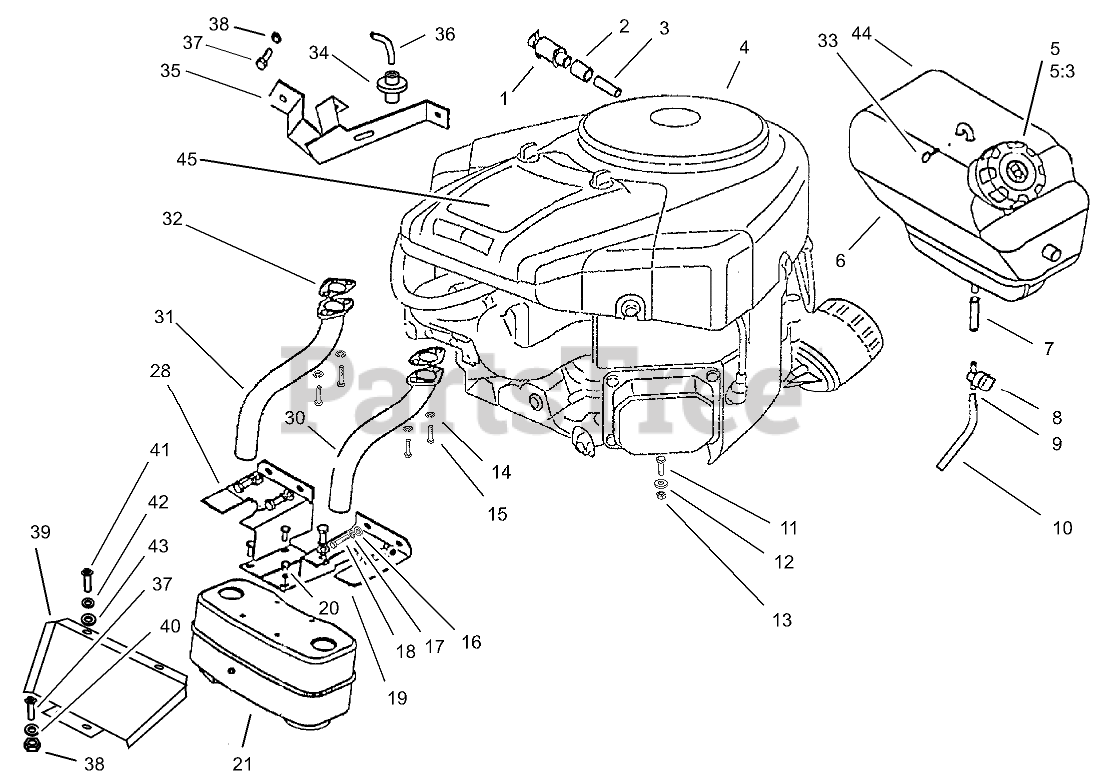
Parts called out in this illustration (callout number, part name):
1	VALVE-OIL DRAIN
2	COUPLER-OIL DRAIN
3	FITTING-OIL DRAIN
4	Engine-Briggs, Intek, 2cyl
5	GAS CAP ASM
5:3	GASKET-CAP, GAS
6	TANK-FUEL
7	LINE-FUEL
8	VALVE-TANK, FUEL
9	CLAMP-LINE, FUEL
10	LINE-FUEL
11	BOLT-HHF
11	SCREW
12	WASHER-PLAIN
13	NUT-LOCK, NI
14	WASHER-SPRING
15	SCREW-HH
16	WASHER-PLAIN
17	WASHER-SPRING
18	SCREW-HH
19	GUARD-MUFFLER, LH
20	SCREW-HWH
21	MUFFLER
28	GUARD-MUFFLER, RH
30	TUBE-EXHAUST, LH
31	TUBE-EXHAUST, RH
32	GASKET-EXHAUST
33	PIN-HAIR
34	Filter-Fuel
35	Bracket
36	LINE-FUEL
37	SCREW-HH
38	NUT-LOCK
39	SHIELD-HEAT
40	WASHER-PLAIN
42	WASHER-FLAT
43	NUT-LOCK
44	TANK-FUEL W/CAP
45	DECAL-ENGINE
